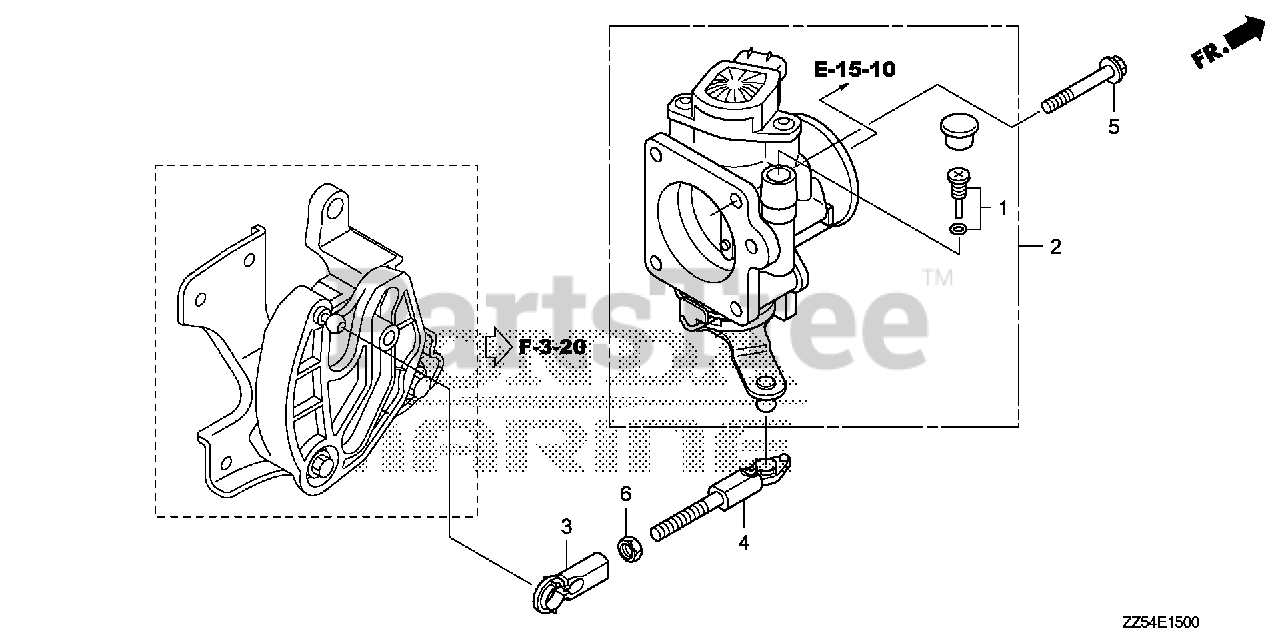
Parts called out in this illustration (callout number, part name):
2	BODY ASSY., THROTTLE
3	LINKAGE, PIVOT
4	ROD, THROTTLE
5	BOLT, FLANGE (6X50)
6	NUT, HEX. (5MM)
